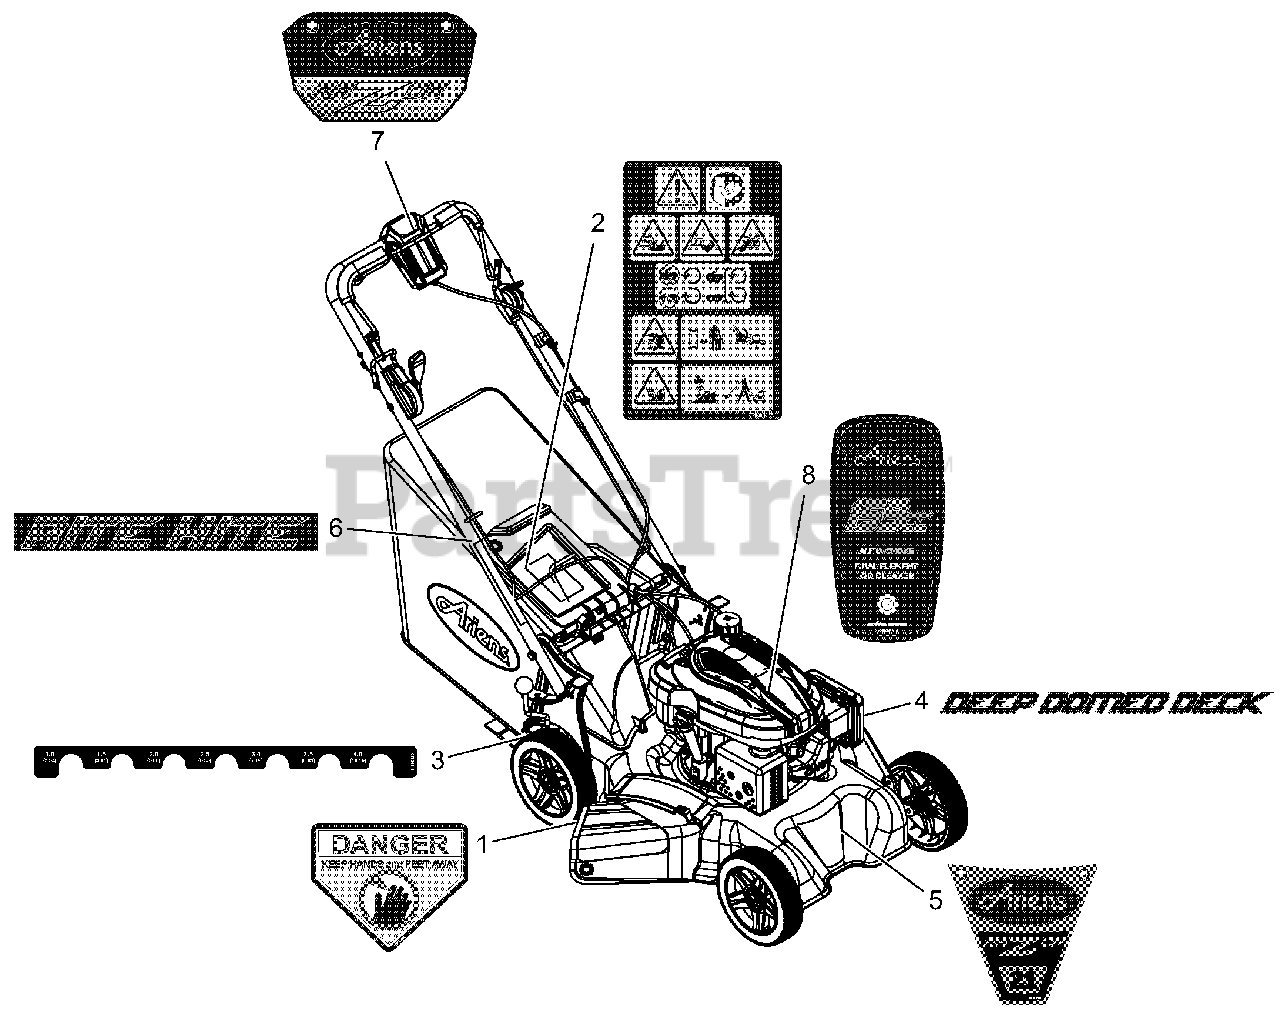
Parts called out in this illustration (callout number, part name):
1	DECAL, DANGER
2	DECAL,MAIN SAFETY_WAW LM
3	DECAL, HOC
4	DECAL, DEEP DOME DECK
5	DECAL, ARIENS RAZOR STYLE
6	DECAL, RITE HITE
7	DECAL, ARIENS RAZOR - SMALL
8	DECAL, ENGINE STYLE - ARIENS
